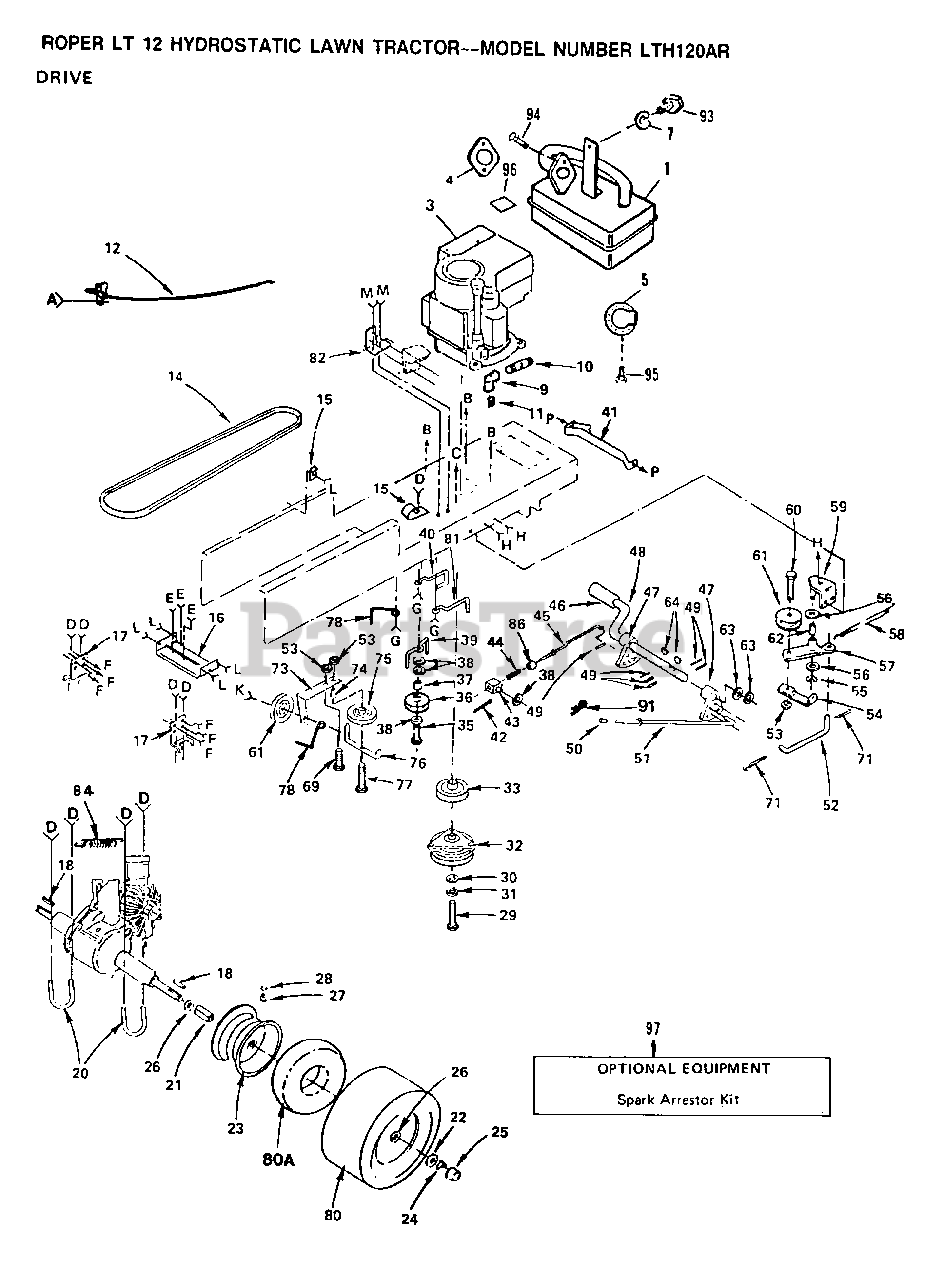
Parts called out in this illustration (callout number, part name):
1	MUFFLER LT
3	ENGINE 12 H.P. TYPE 0201-01
5	DEFLECTOR.222573
7	LOCKWASHER
9	ELBOW
10	PIPE NIPPLE LT
11	PLUG OIL DRAIN
14	V BELT T
15	CLIP T
17	BRKT, TRANSAXLE
18	SQ KEY STD
21	SPACER HYT
22	WASHER T
24	E RING HYT
25	HUB CAP
26	WASHER
27	VALVE STEM LT
28	VALVE CAP
30	WASHER T
31	LOCKWASHER
35	BOLT
37	SPACER T
38	WASHER
39	BELT KEEPER LT
40	KEEPER BELT HYT
42	COTTER PIN
43	TRUNION HYT
44	SPRING BRAKE HYT
45	BRAKE ROD HY
46	PEDAL COVER T
47	ARM BRAKE LT
48	SHAFT, FOOT PEDAL
50	PLUNGER CAP T
52	"LINK, CLUTCH T"
55	KLIP RING
56	WASHER LT
58	"SPRING, RETURN LT"
62	"LY, BEARING"
69	BOLT
71	No Desciption for Part
73	BRKT IDLER HYT
74	SPACER SPLIT LTV
75	IDLER.PULLEY.LT
76	KEEPER BELT HYT
77	BOLT - HEX 3/8 - 16 X 3
78	BELT RETAINER GT
80A	TUBE.18X9.5-8
81	BELT KEEPER T
82	BRACKET LT
86	No Desciption for Part
94	SCREW LT
95	SCREW LT
96	DECAL.ENG.271967
97	SCREEN
